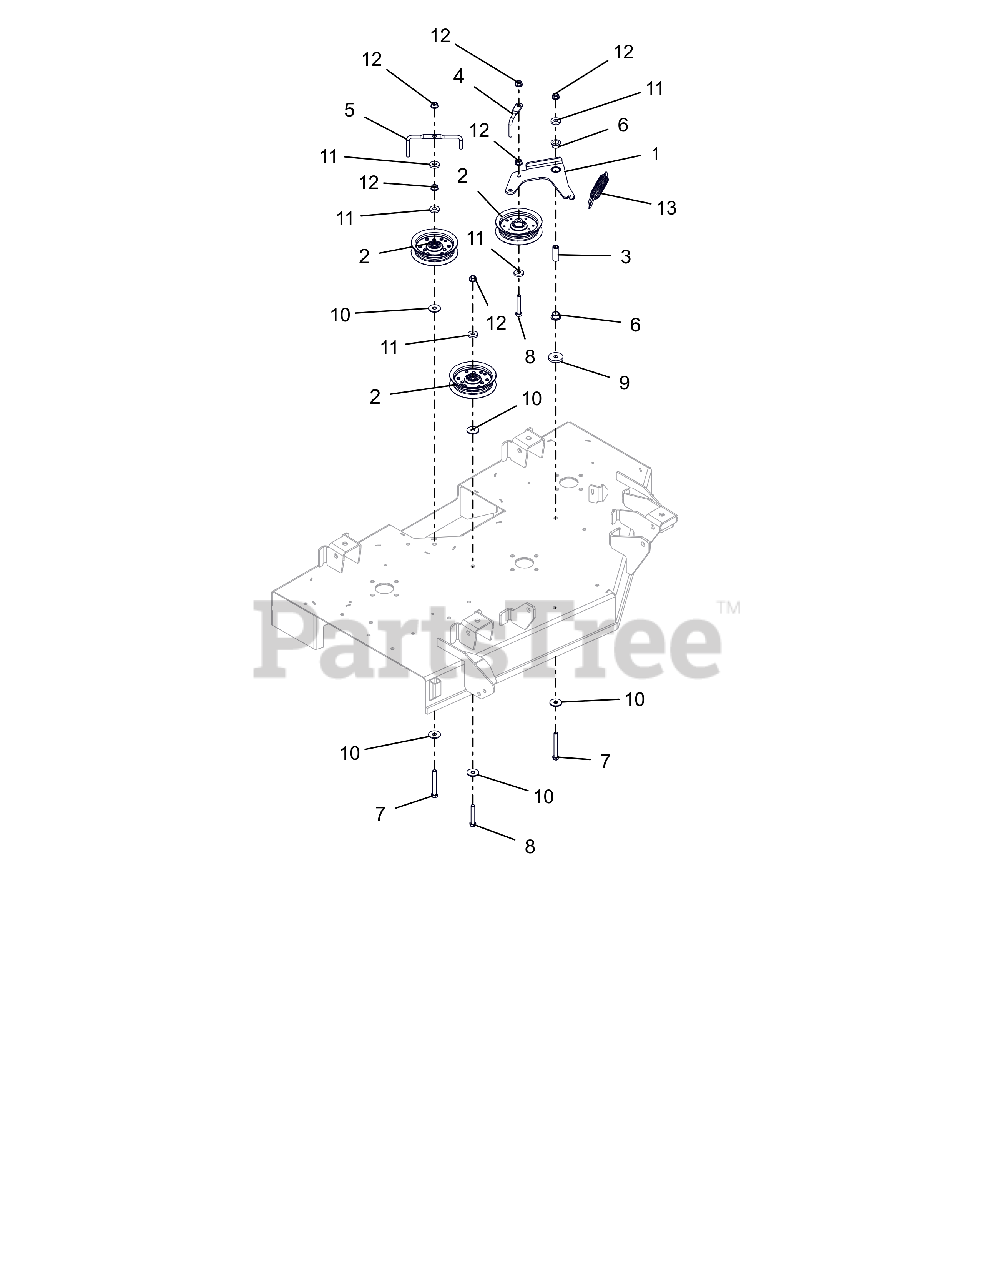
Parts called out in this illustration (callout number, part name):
1	WLDMT, IDLER ARM-42"
2	ASM, IDLER 4"
3	SPACER, .375IDX.625ODX1.66 PM
4	WIREFORM, BELT FINGER
5	WIREFORM, BELT FINGER
6	BSHG-FLG, .625X.750X.500X1.00
7	BLT-HEX .38-16X3.00 GR5 FTH YZ
8	@BLT-HEX .38-16X2.25 GR5 YWZC
9	WSHR,FLT STL.406X1.50X.245YWZC
10	WSHR FL STL .406X1.25X.10ZC120
11	WSHR-FL-STL .406X1.00X.188 YWZ
12	NUT-LK-TOP-FLG .38-16 ZC120
13	SG-TENS .135X.98X6.0 WLD 62
